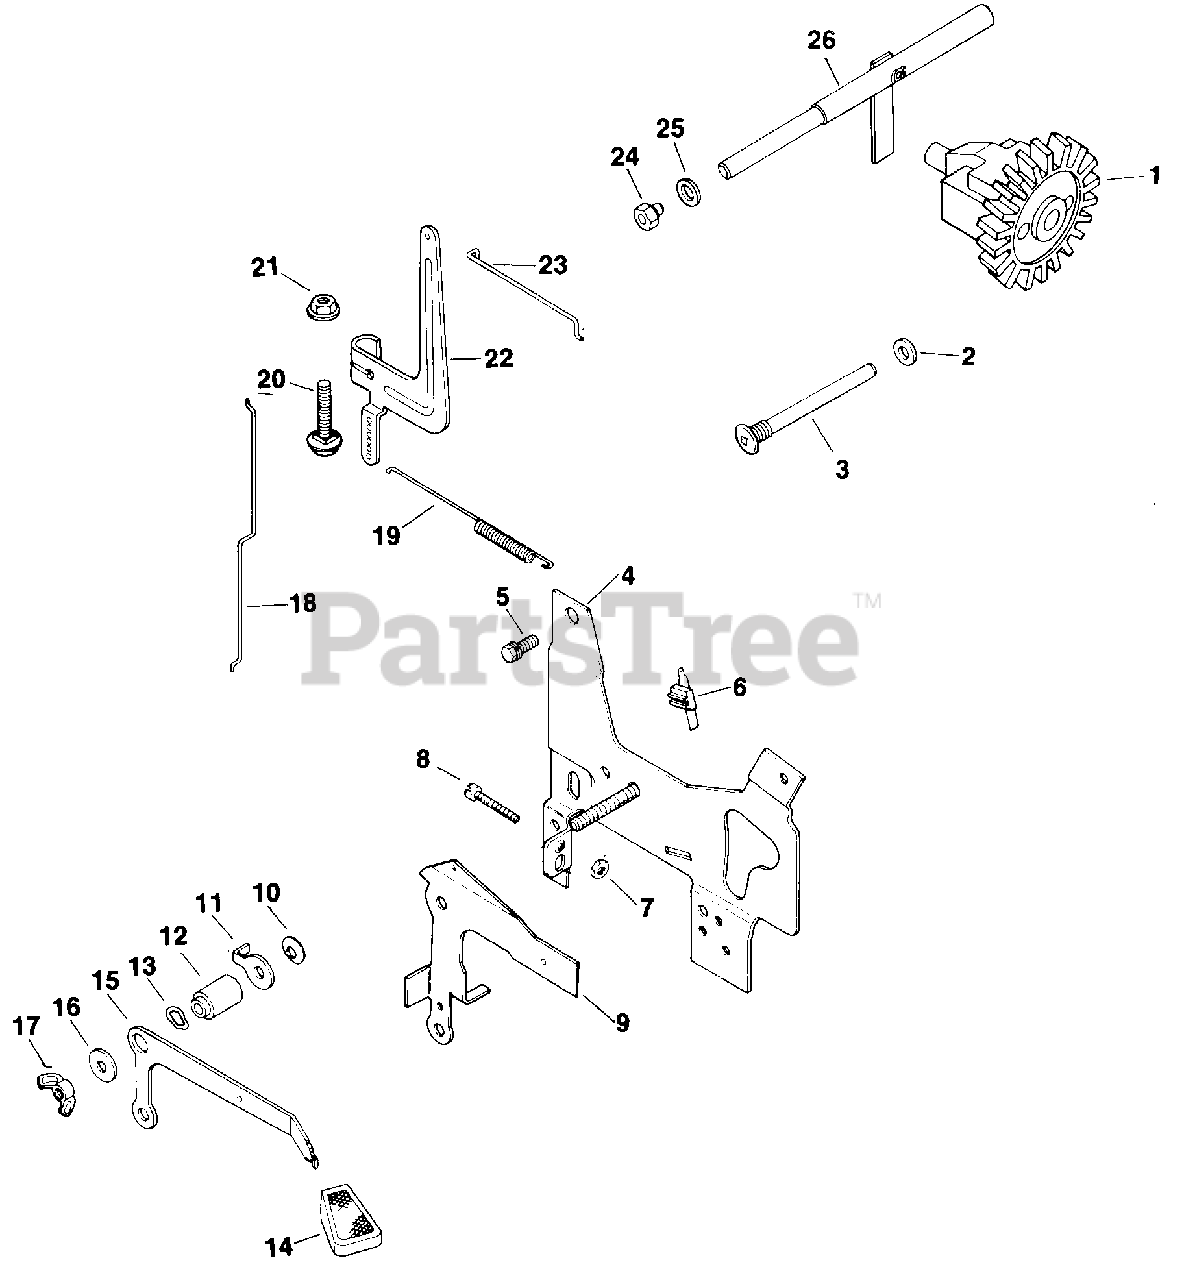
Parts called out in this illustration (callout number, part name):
1	Kit, Governor Gear
2	Washer, Plain 1/4
3	Pin, Governor
4	Bracket, Speed Control
5	Screw, Hex. Hd. Sems 1/4-20 x 1/2
6	Switch, Kill
8	Screw, Fillister Hd. 8-32 x 1
9	Lever, Speed Control
10	Washer, Wave
11	Tab, Locking
12	Spacer, Speed Control
13	Washer, Wave
15	Lever, Choke Control
16	Washer, Plain 1/4
18	Rod, Choke Link
19	Spring, Governor
20	Bolt, Round Head
22	Lever, Governor
23	Link, Governor
24	Bushing, Governor
25	Washer, Plain 1/4
26	Shaft Governor Cross
